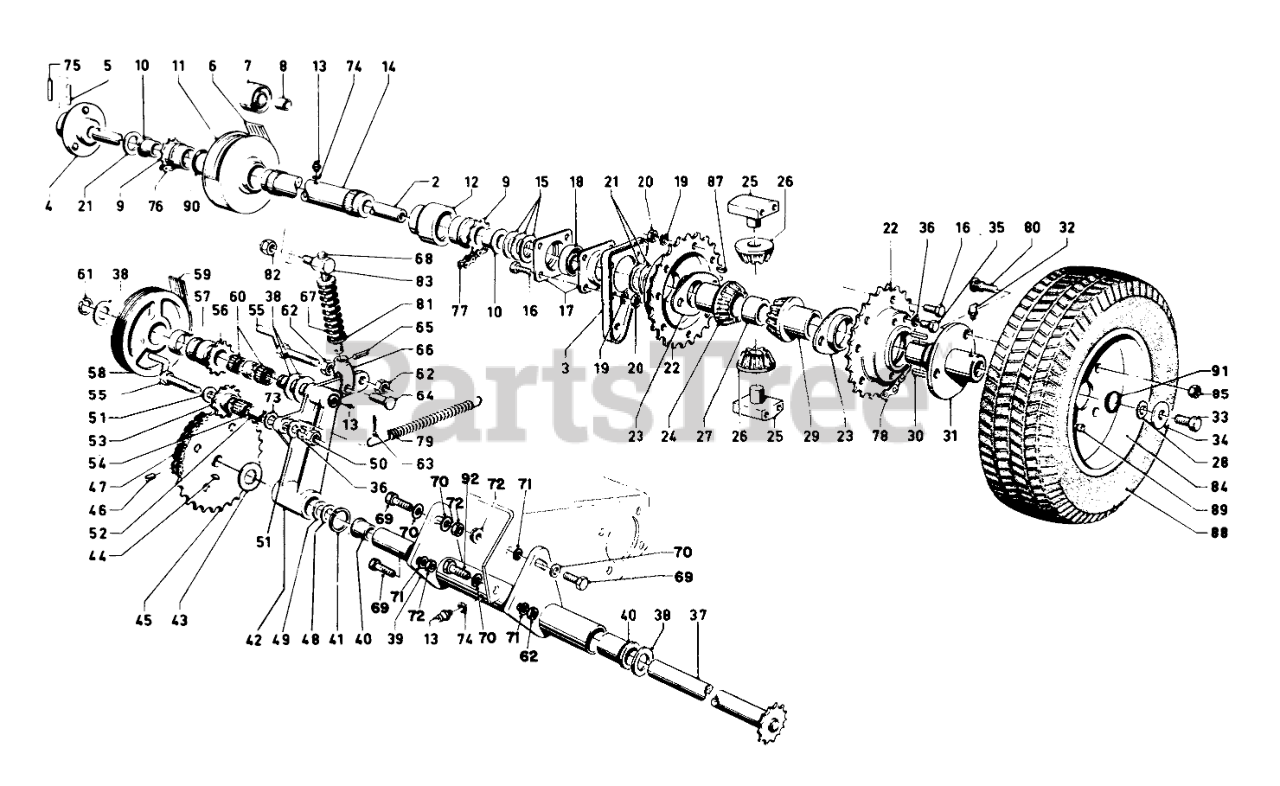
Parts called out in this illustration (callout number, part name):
3	Bracket
4	Hub, Right Side (Incl. Ref. #80)
5	PIN-ROLL, SLOTTED
6	REEL BELT
7	REEL IDLER R
8	TOL RING
9	Sprocket (Incl. Ref. #10)
10	3/4IDX1LG FLANGE BSHG
11	Pulley & Hub Assy. (Incl. #90)
13	FITTING-GREASE
14	REEL DRIVE TUBE R
15	WASHER-THRUST
16	SCREW-HH
17	Bearing Retainer
18	Bearing
19	WASHER-LOCK
20	NUT-HEX
21	THRUST WASHER
22	Sprocket Case, Diff. (Incl. Ref. #23)
23	Bushing
24	DIFF SIDE GEAR
25	Carrier, Diff. Pinion
26	Pinion
27	Spacer
28	WASHER-LOCK, INTERNAL
29	LH DIFF SIDE GEAR
30	KEY-SQUARE
31	Hub, Left Side (Incl. Ref. #80)
32	FITTING-LUBE, 45 DEG
33	SCREW-HH
34	WASHER-FLAT
35	SCREW-HH
36	WASHER-LOCK
37	Countershaft & Sprocket
38	THRUST WASHER
39	Countershaft Tube Assembly (Incl. Ref. #40)
40	Bushing
41	RING-SNAP
42	Bell Crank Assembly (Incl. Ref. #13)
43	THRUST WASHER
44	KEY-WOODRUFF
45	LARGE SPROCKET ASM
46	Set Screw
47	TRACTION CHAIN
48	THRUST WASHER
49	THRUST WASHER
50	NUT-HEX
51	WASHER-PLAIN
52	SPINDLE
53	Sprocket, Idler (Incl. Ref. #54)
54	Bearing
55	Belt Guide
56	TRACTION SPROCKET
57	Ring Tolerance
58	TRACTION PULLEY
59	TRACTION BELT
60	.625 NEEDLE BEARING
61	Snap Ring
62	NUT-JAM
63	PIN-COTTER
64	PIN-CLEVIS
65	PIN-ROLL, SLOTTED
66	CLEVIS
67	COMP SPRING R
68	ROD & FLANGE WA
69	SCREW-HH
70	WASHER-FLAT
71	WASHER-LOCK
72	NUT-KEPS
73	WASHER-FLAT
74	WASHER-LOCK
75	PIN-ROLL
76	Chain, Reel Drive-Front
77	Chain, Reel Drive-Rear
78	Chain
79	SPRING-EXTENSION
80	DRIVE STUD
81	WASHER-FLAT
82	NUT-LOCK, NI
83	Pivot Rod
84	Wheel Disc Assy.
85	LUG NUT
87	KEY-WOODRUFF
88	Tire
89	STEM-VALVE
90	2-1/2X086 EX SNP RING
91	O-RING
92	SCREW-HH
